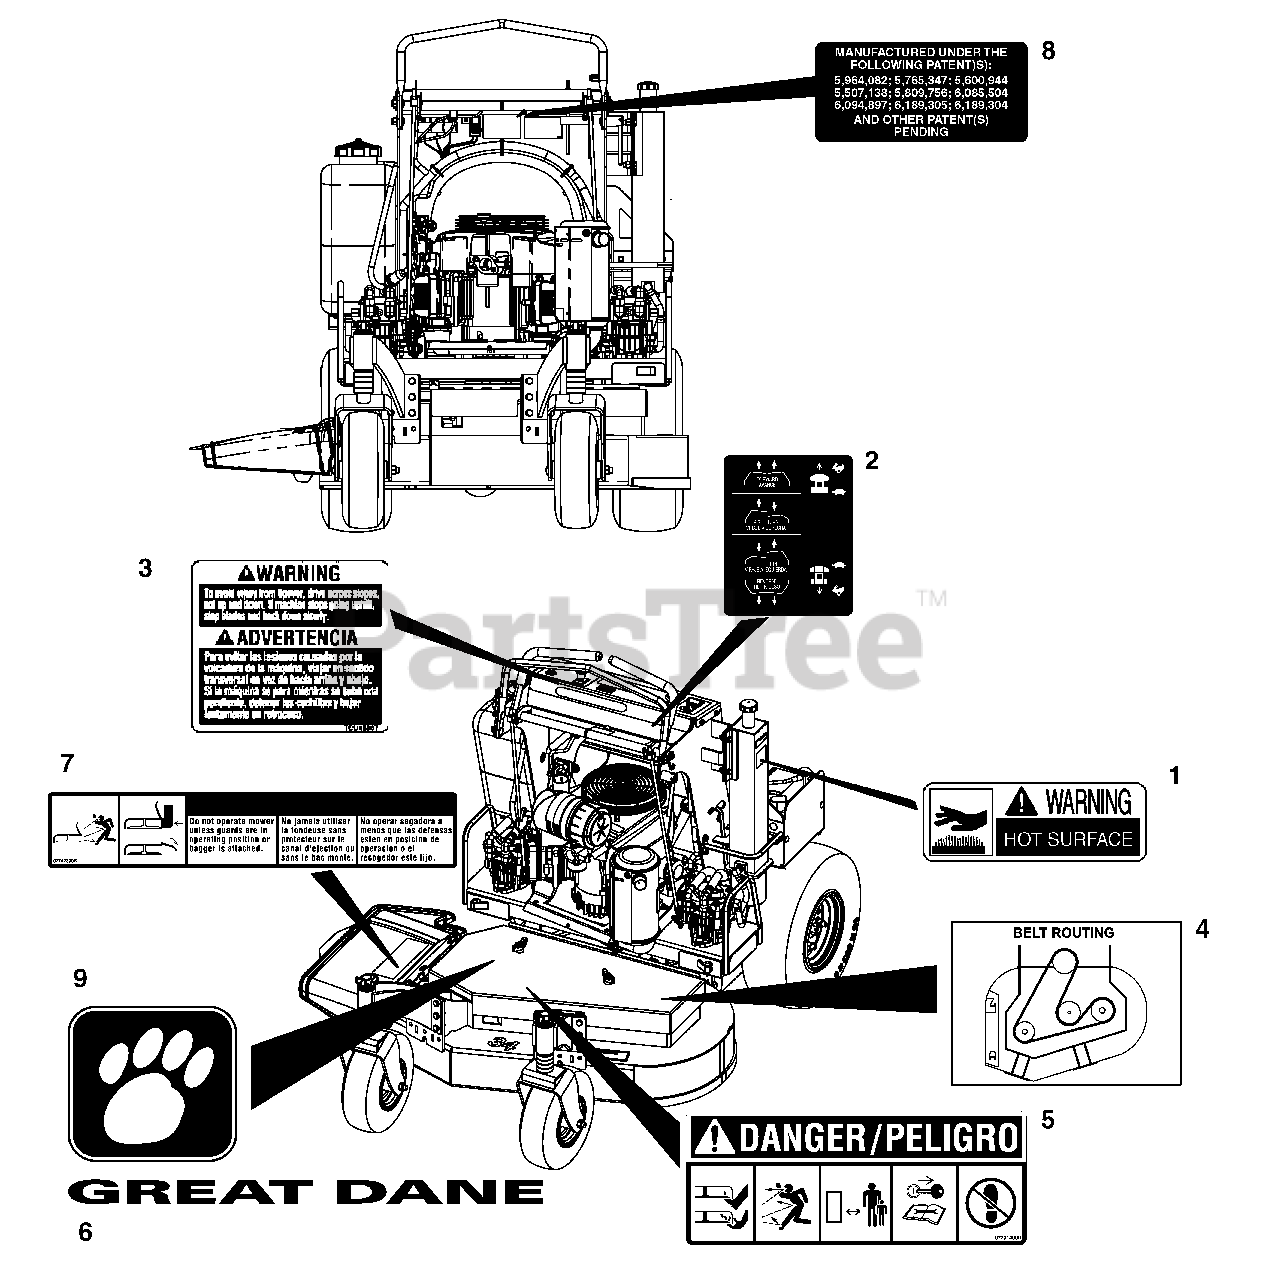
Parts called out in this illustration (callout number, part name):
1	Decal, Warning, Hot Surface
2	Decal, Directional Control
3	Decal, Danger - Avoid Tipover
4	Decal, Belt Path
5	Decal, Warning
6	Decal, Great Dane
7	Decal, Danger - Thrown Objects
8	Decal, Patent
9	Decal, Paw Print
